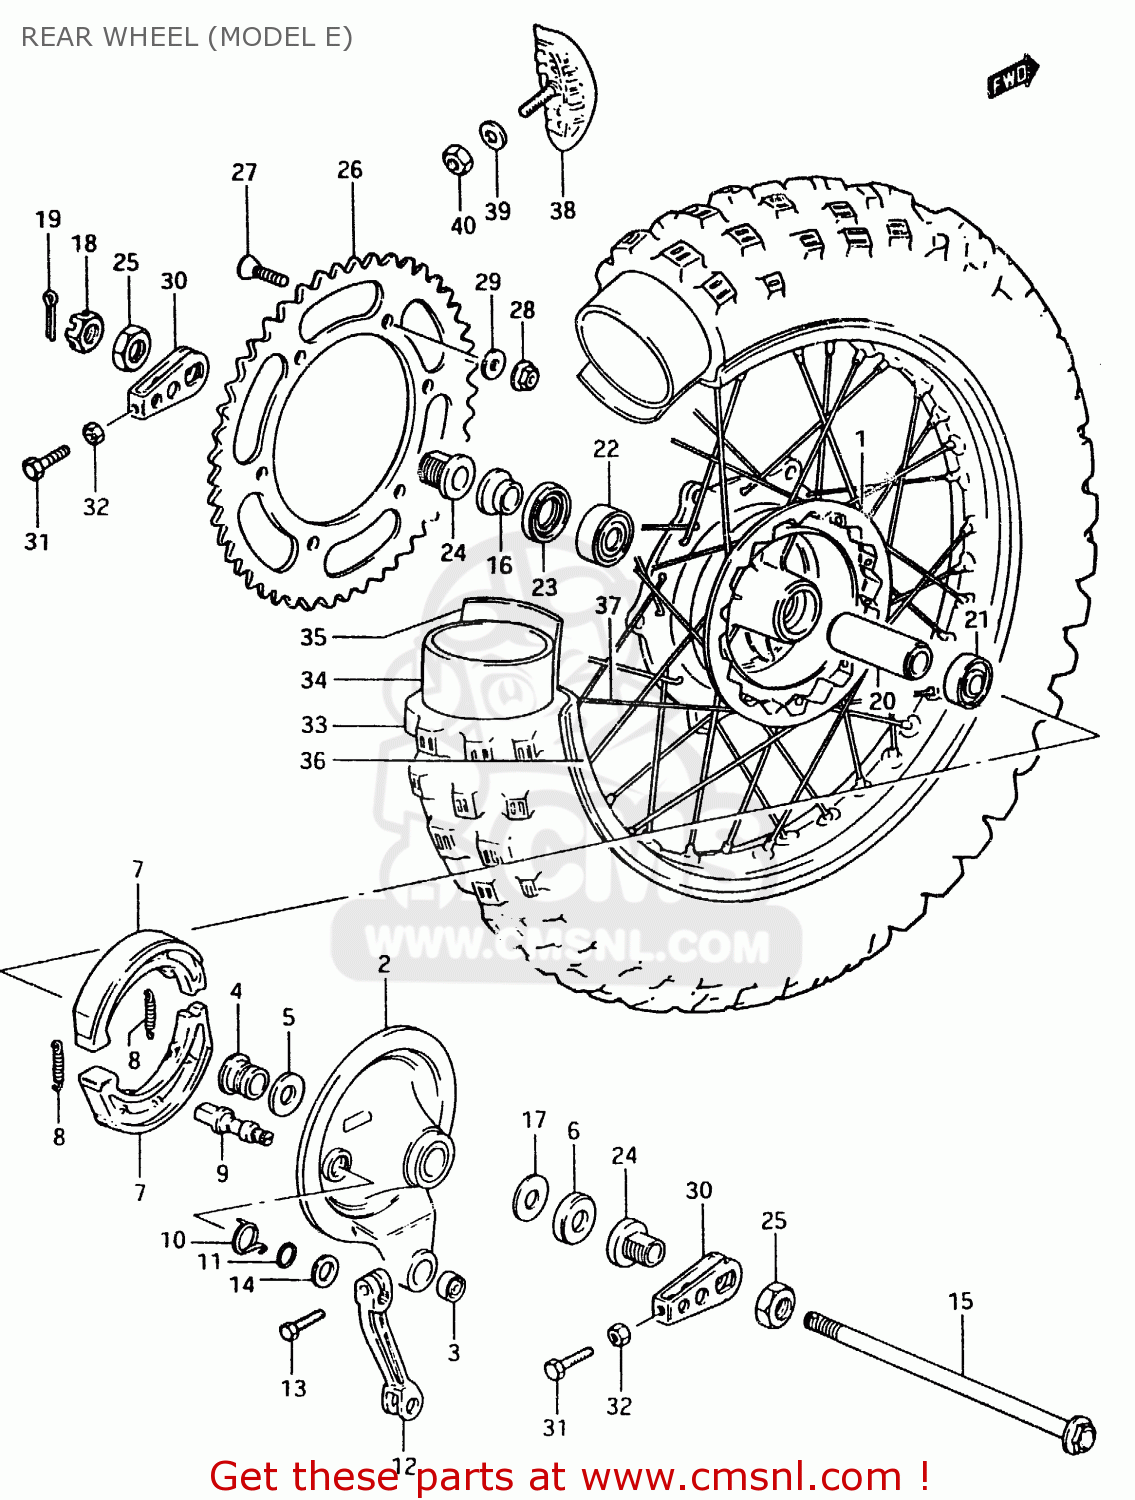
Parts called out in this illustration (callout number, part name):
1	DRUM,REAR HUB
2	PANEL SET
3	SPHERICAL BRNG,TORQUE LINK
4	SPACER,REAR HUB PANEL
5	SEAL,OIL(24X31X5)
6	CVR,RR BRAKE AHR PNL DUST SEAL
7	SHOE,BRAKE
8	SPRING,BRAKE SHOE
9	CAM,FR BRAKE
10	SPRING
11	O RING(D:2.5,ID:11.4)
12	LEVER,REAR BRAKE CAM
13	BOLT
14	WASHER(12.5X20X1)
15	AXLE,REAR
16	SPACER,REAR AXLE,LEFT
17	WASHER
18	NUT
19	PIN,COTTER
20	SPACER,REAR HUB BEARING
21	BEARING
22	BALL BEARING 17X47X22
23	OIL SEAL (25X47X7.5)
24	SPACER,CHAIN ADJUSTER
25	NUT
26	SPROCKET,REAR (NT:46)(AL)
27	SCREW(8X40)
28	NUT
29	WASHER
30	ADJUSTER,CHAIN
31	BOLT
32	NUT
33	TIRE 140/80-18
34	TUBE ASSEMBLY,WHEEL,INNER
35	PROTECTOR,INNER TUBE
36	RIM,REAR WHEEL (2.50X18)(
37	SPOKE SET,REAR WHEEL
38	STOPPER,BEAD
39	WASHER
40	NUT
